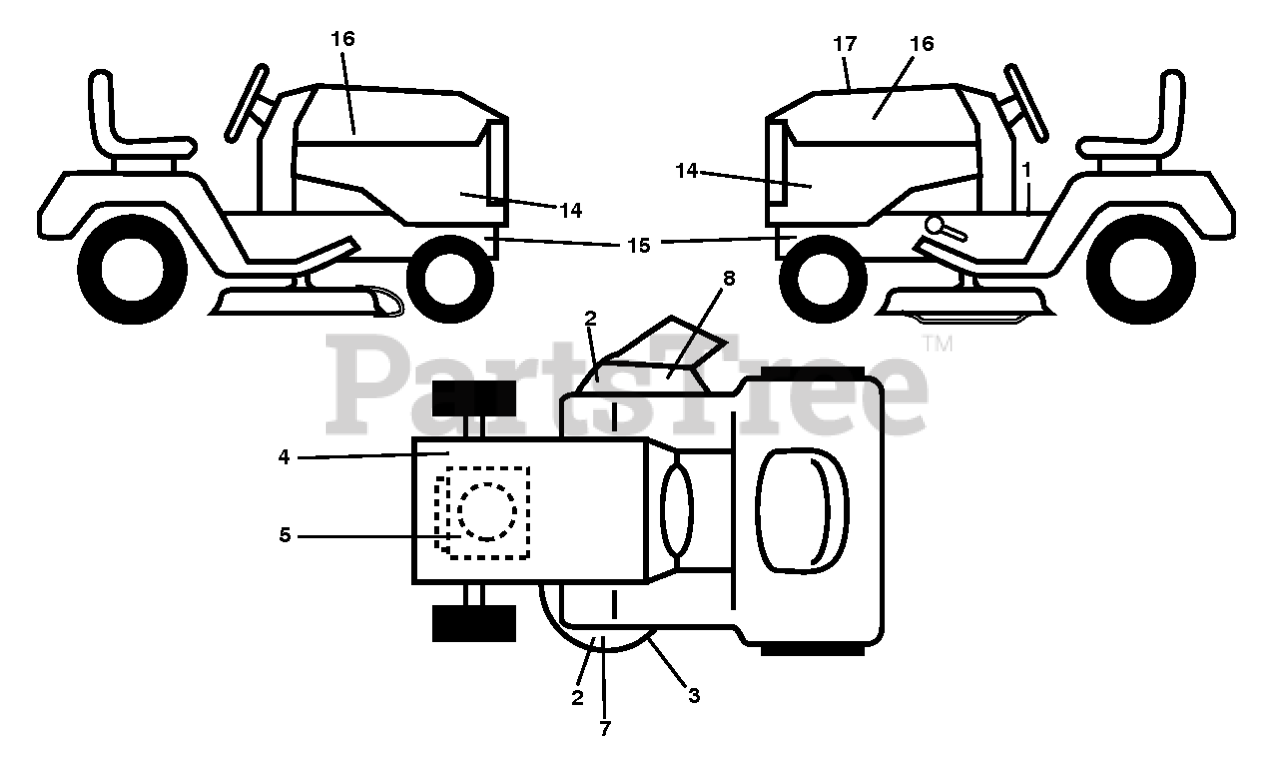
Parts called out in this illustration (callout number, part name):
1	DECAL.TRACTOR.SADDLE
2	DECAL.DECK.CLEARCUT.NOSTEP
3	DECAL.MOWER.SCH.48/54.PREM
4	DECAL ENG.DECAL.B&S.ENDURANCE.
5	DECAL.ENGINE.WARNING
7	DECAL DECK DECAL DECAL.48DECK.
8	DECAL.TRACT/ZTR.DECKWARN.HUSQ
14	DECAL TRACTOR SIDE PANEL DECAL
15	DECAL.CHASSIS.HOT.MUFFLER
16	DECAL.BADGE.170MM.TEXTLOGO.
17	DECAL DECAL.RPL.BSM44.INTK.872
